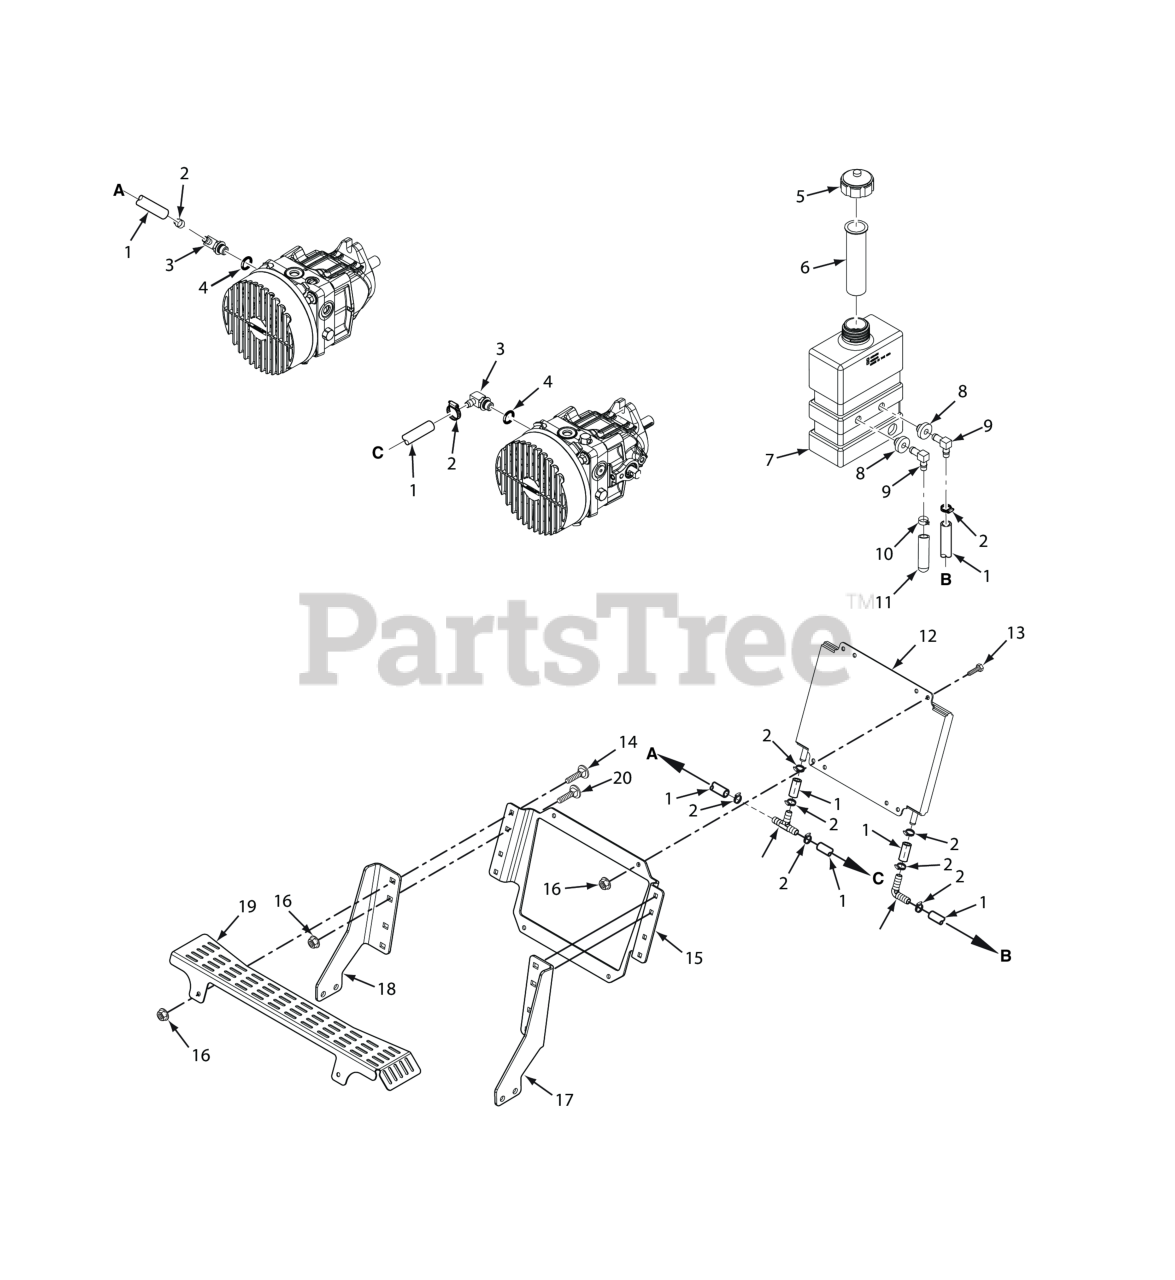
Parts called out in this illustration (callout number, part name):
1	Hose, 3/8" ID - 10-1/4" Long (Order By The Inch)
2	Clamp, .69" Max. / .25" Min. Dia.
3	Elbow, 90 Degree - 9/16" O-Ring x 3/8" Hose
4	"O" RING, 5/64 X 15/32 ID
5	CAP, HYDRAULIC TANK
6	Insert, Filler Neck
7	Elbow, 90 Degree, 9/16-18 JIC x 9/16 O-Ring
8	Bushing, 0.56" Dia. Viton
9	Elbow, 90 Degree, 9/16-18 JIC x 9/16 O-Ring
10	Clamp, Fuel Hose 1/4" Hose I.D.
11	Cap Plug, .375 x 1.50
12	Cooler, Transmission (52V/61V)
13	BOLT, HEX HEAD, 1/4-20 X 3/4 GR.5
14	Serr. Fl. Hex Head CPSCR, 1/4-20 x 3/4"
15	Mounting Bracket, Oil Cooler (air cooled)
16	NUT, 1/4-20 SERRATED FLANGE HEX HEAD
17	Mounting Bracket, Cooler - LH
18	Mounting Bracket, Cooler - RH
19	Screen Guard, Briggs & Stratton 31&35BV
20	Bolt, Carriage 1/4-20 x 1/2"
